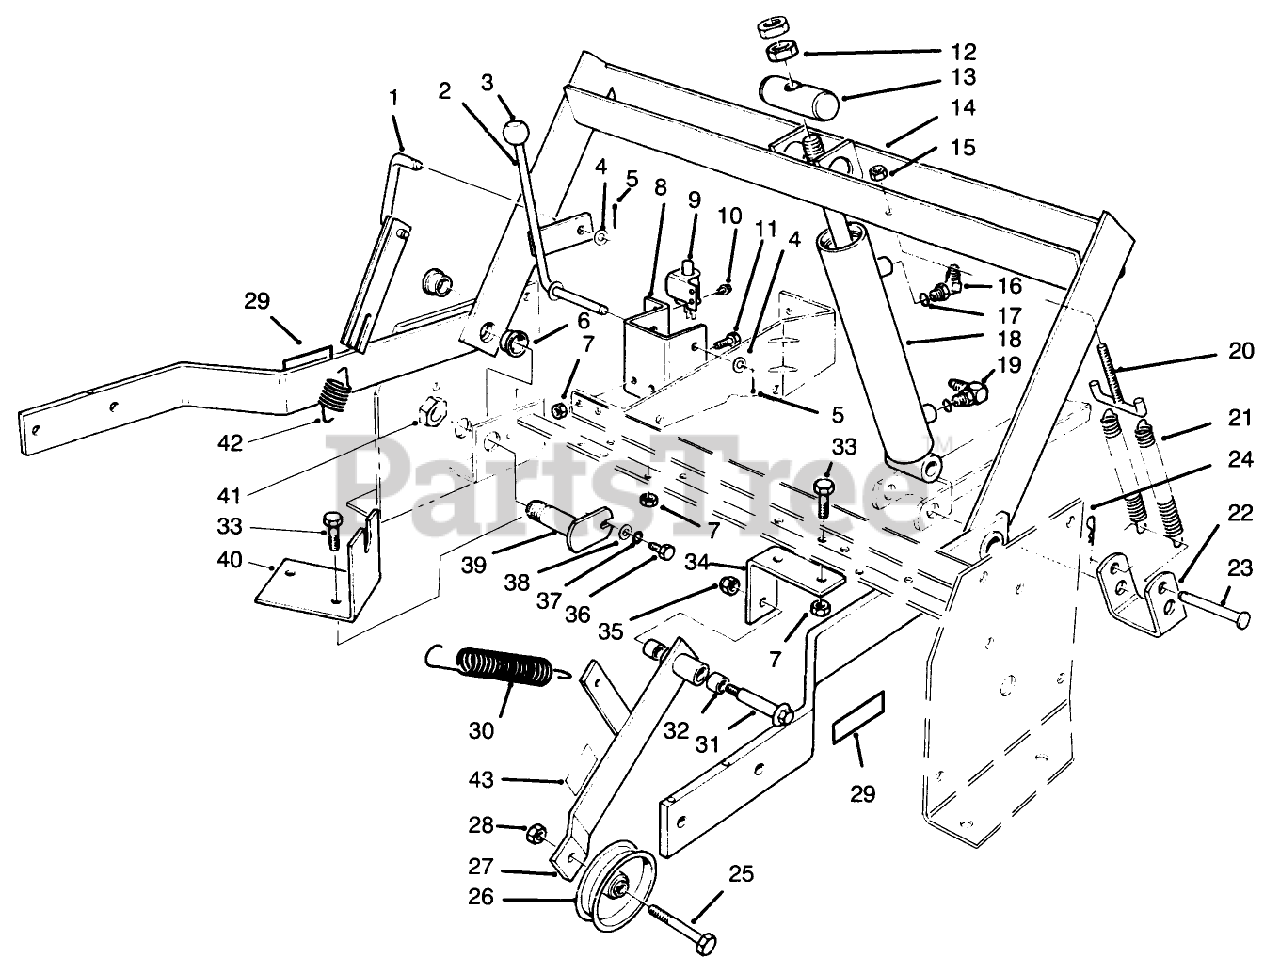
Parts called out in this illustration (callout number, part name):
1	Link-Parking Brake
2	Brake Lever
4	WASHER-FLAT
5	PIN-COTTER
6	BEARING-FLANGE
7	NUT-LOCK, NI
8	Bracket-Parking Brake
9	SWITCH-BRAKE, PARKING
10	SCREW-TAPTITE
11	SCREW-HH
12	NUT-JAM
13	CYL.PIVOT PIN
14	Frame-Lift (Incl. Ref. #6)
15	NUT-HEX, SIDE DEFORM
16	FITTING-45 DEG
17	O-RING
18	CYLINDER - LIFT
19	FITTING-ELBOW, 90
20	T-HOOK W A
21	SPRING_EXTENSION
22	SPRING BRACKET
23	PIN-CLEVIS
24	PIN-HAIR
25	SCREW-HH
26	PULLEY-IDLER
27	Lever-Idler (Incl. Ref. #43)
28	NUT-LOCK, NI
29	WARNING DECAL
30	IDLER EXT SPRING
31	BOLT-WHEEL
32	BUSHING
33	SCREW-HH
34	JACKSHFT IDLR BRKT
35	NUT-LOCK
36	SCREW-HH
37	WASHER-LOCK
38	WASHER-FLAT
39	Pin-Pivat
40	TRACT CABLE BRKT
41	NUT-LOCK, NI
42	PARK BRAKE SPRING
43	DECAL-WARNING
